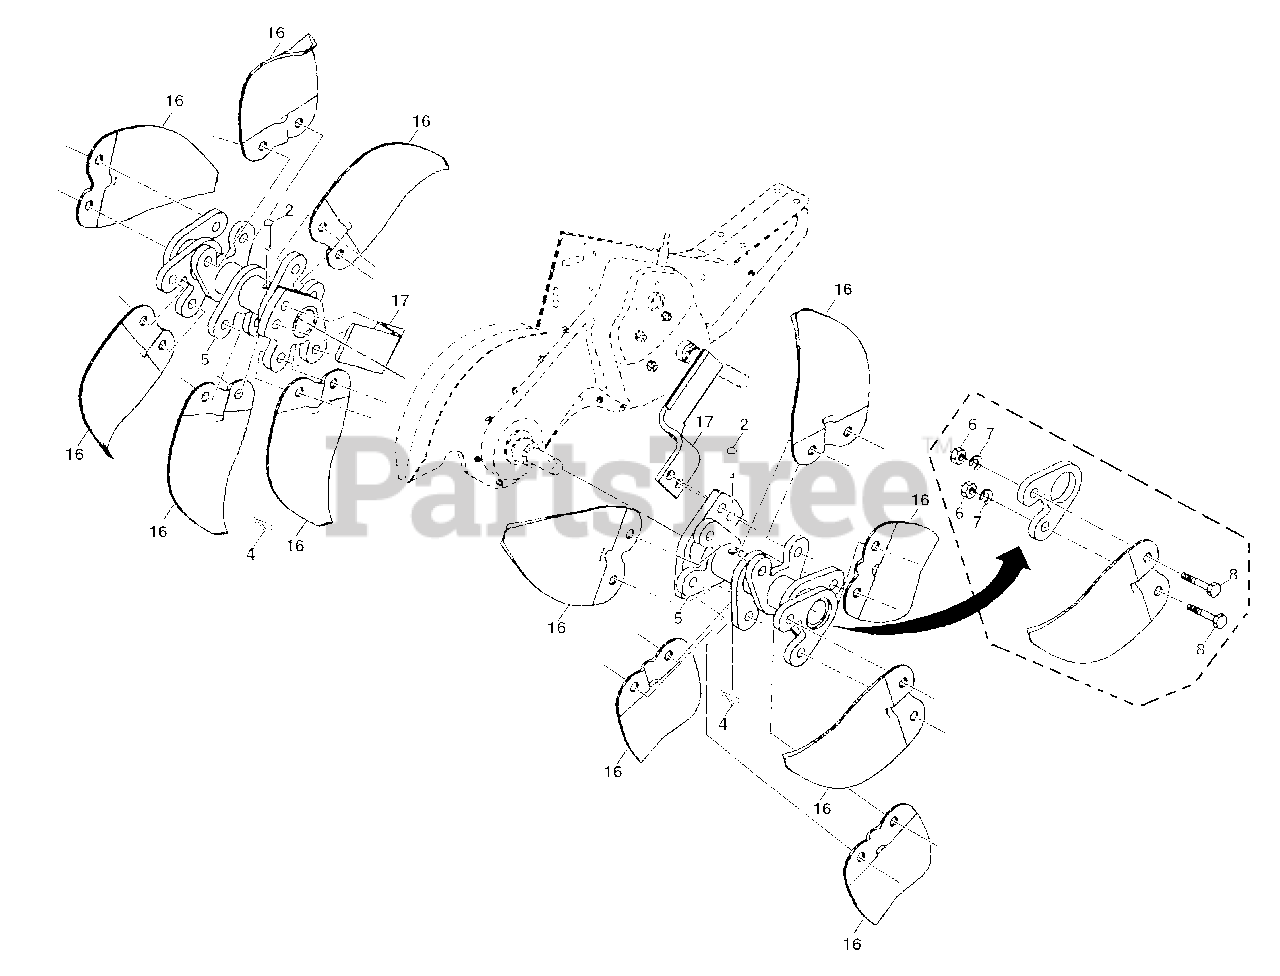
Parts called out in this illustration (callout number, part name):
2	Pin, Shear
4	Clip, Hairpin
5	Hub Assembly
6	Nut, Hex 3/8-24
7	Washer, Lock 3/8
8	Bolt, Hex 3/8-24 x 1
16	Tine, Spade
17	Tine, Cleaning
